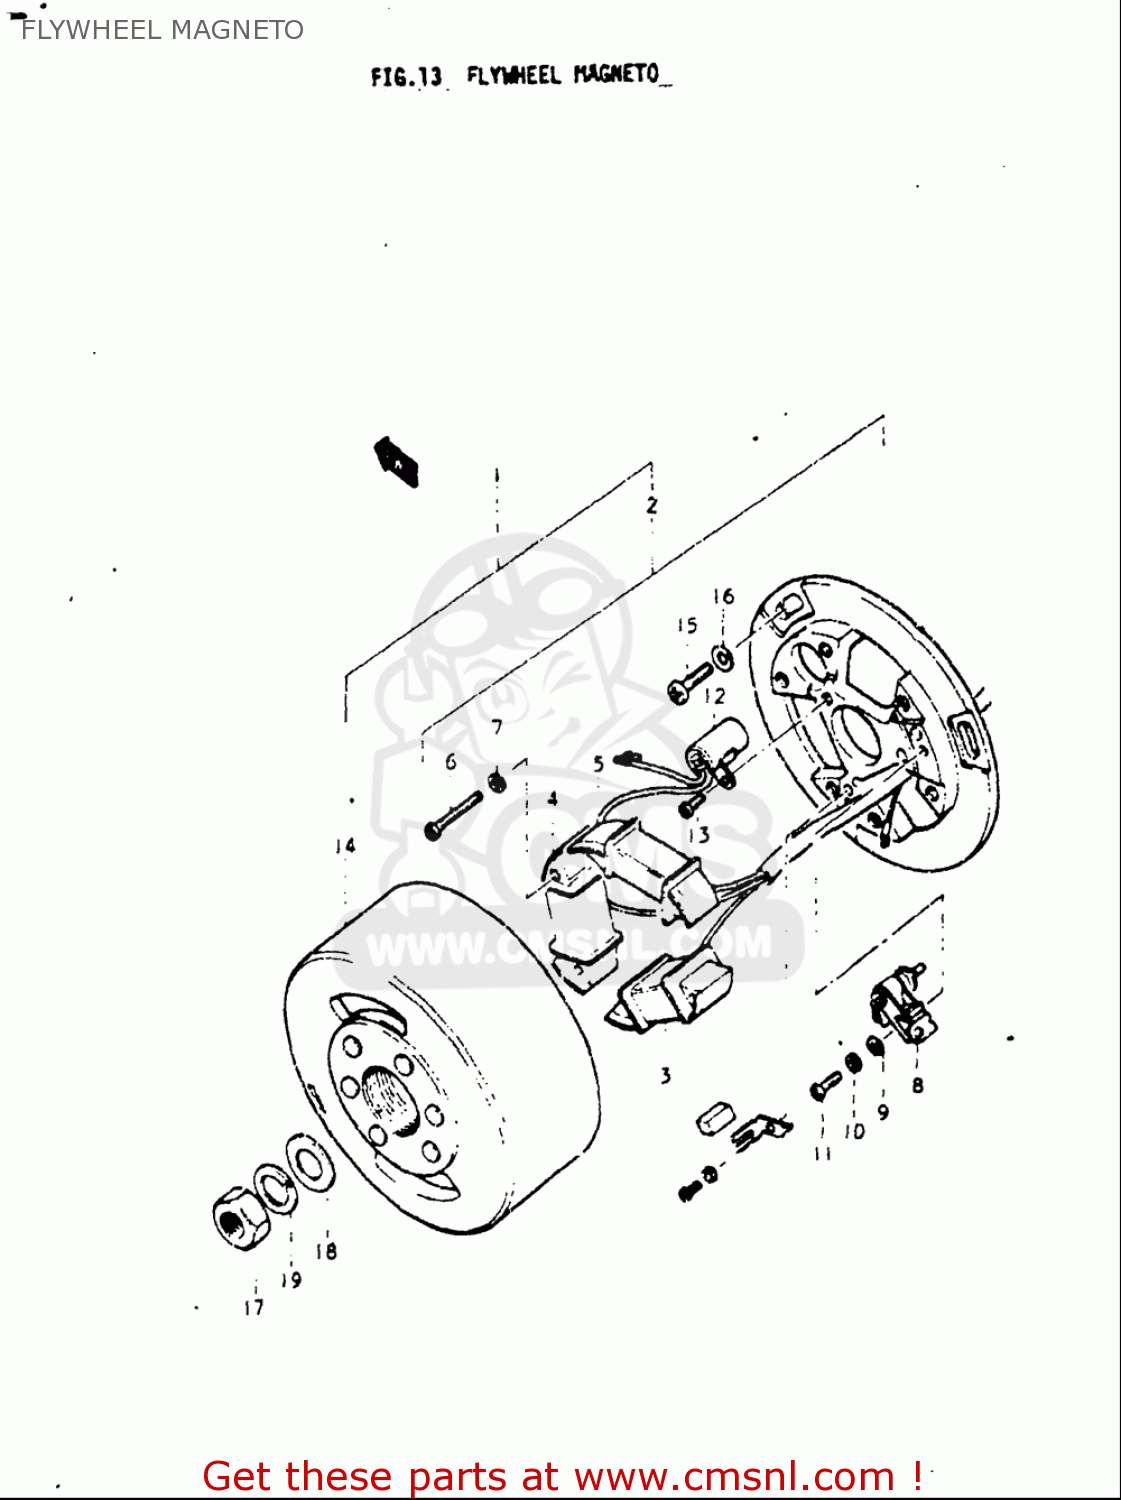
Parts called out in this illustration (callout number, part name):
6	SCREW(4X30)
7	WASHER,LOCK
8	POINT ASSY,CONTACT
9	WASHER
10	WASHER,LOCK
11	.SCREW
12	CONDENSER
13	SCREW
15	SCREW
16	WASHER
17	NUT
18	WASHER
19	WASHER,LOCK
